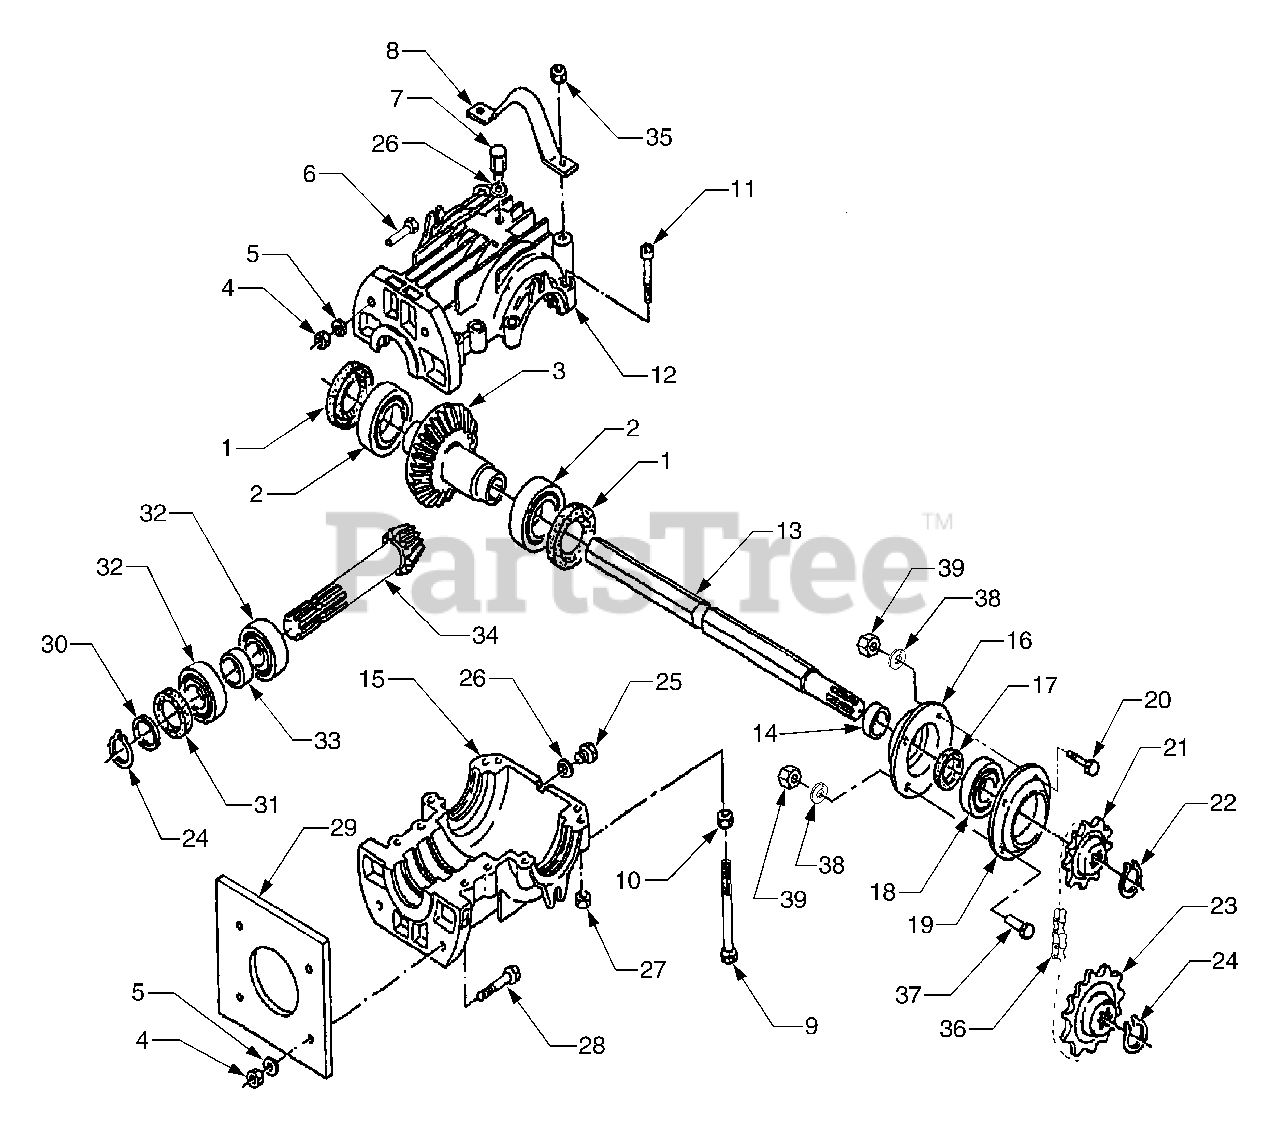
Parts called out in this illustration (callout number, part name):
3	Ring Gear Complete 540 rpm
4	Nut M12
6	Bolt, 12 x 35
7	Breather Cap
9	Bolt 10x140
12	Gearbox Housing with Hole
13	Hexagonal Shaft
15	Gearbox Housing without Hole
19	Outer Cover - Left
20	Bolt M10 x 45
21	Sprocket Z14 540 rpm
22	Snap Ring 30 External
23	Sprocket Z16 540 rpm
24	Snap Ring 35 External
29	Metal Cover
30	Spacer Washer
34	Pinion Gear
36	Chain ASA 60x46
37	Bolt M10 x 25
38	Lockwasher, 10mm
